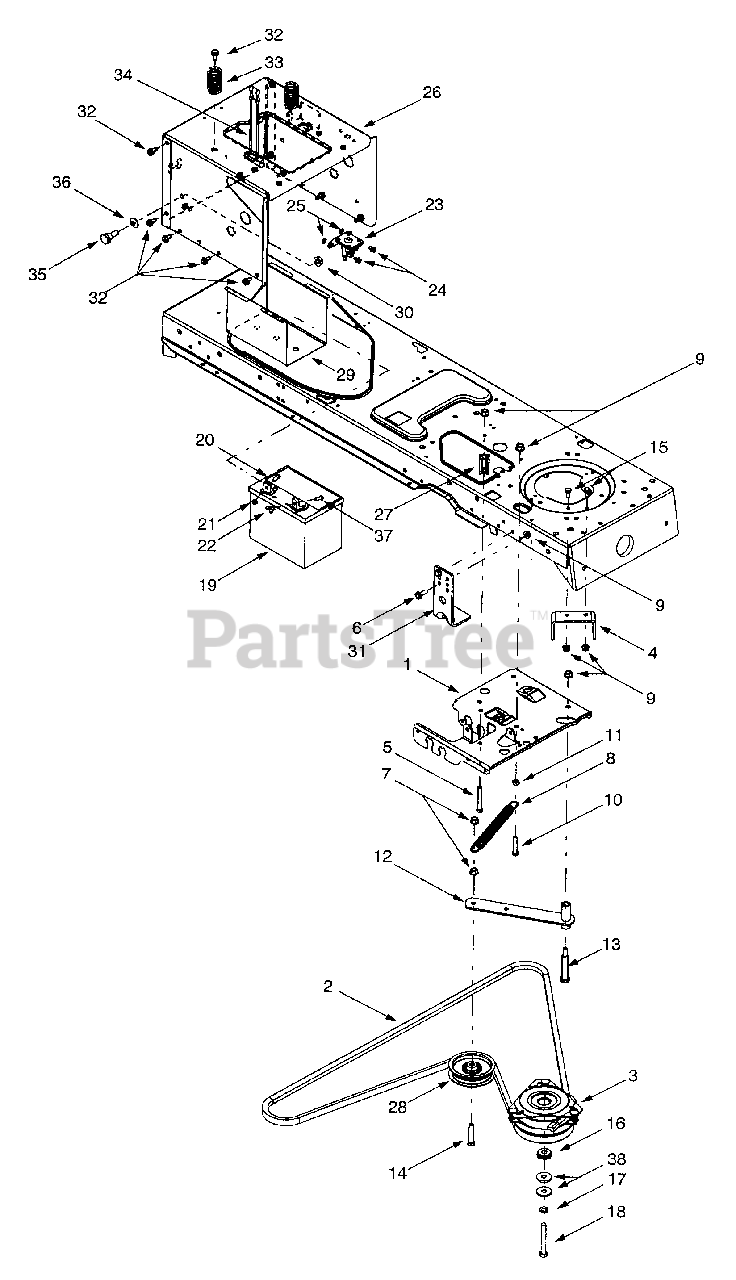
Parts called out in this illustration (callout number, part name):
2	PTO Belt
3	Electric PTO Clutch
6	Hex Head Washer Screw, 5/16-18 x .875
7	Flange Lock Nut, 3/8-16
8	Extension Spring, .62 x 5.62
9	Flange Lock Nut, 5/16-18
10	Hex Cap Screw, 5/16-18 x 1.75
11	Hex Nut, 5/16-18
14	Hex Cap Screw, 3/8-16 x 2.0
15	Hex Cap Screw, 5/16-18 x .625
16	Shoulder Spacer, 1.38 x .445 x .36
17	Lock Washer, 7/16
18	Hex Cap Screw, 7/16-20 x 3.25 (Grade 5)
19	12-volt Battery, 270 CCA
20	Hex Cap Screw, 1/4-20 x .62
21	Hex Sems Nut, 1/4-20
22	Wing Nut, 1/4-20
23	Solenoid, 12-Volt, 100 Amp
24	Self Tapping Screw, 1/4-20 x.5
25	Lock Washer, 1/4
28	Idler Pulley, 3.5
32	Self Tapping Screw, 5/16-18 x .625
33	Compression Spring, 1.28 x 3.5
34	Battery Strap
35	Shoulder Screw, .625 x .5, 7/16-20
36	Bell Washer, .45 x 1.0 x .062
37	Shoulder Screw, 1/4-20, .25 x .15
38	Flat Washer, .45 x 1.25 x .164
